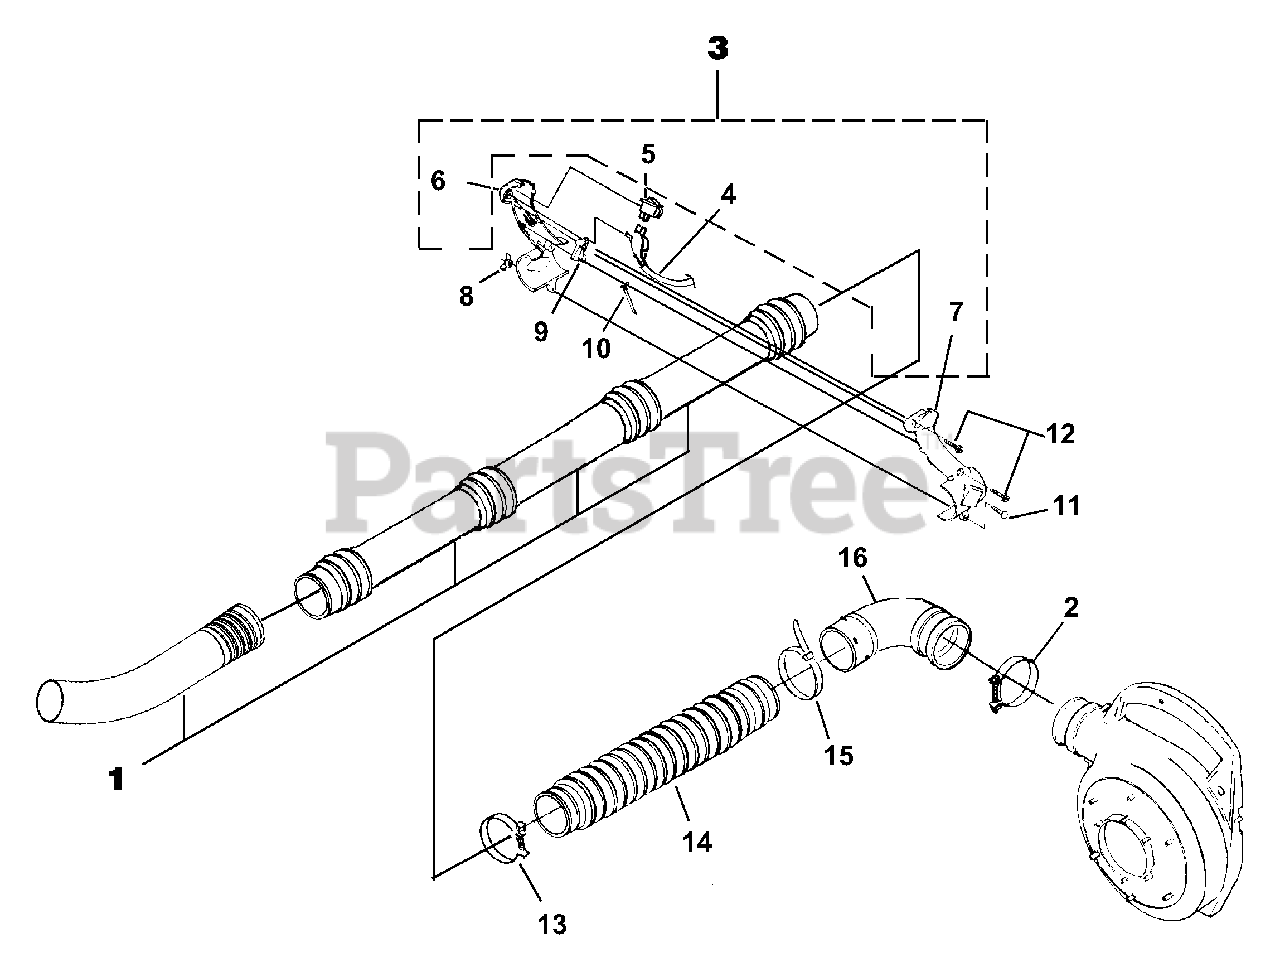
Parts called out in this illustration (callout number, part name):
1	BLOWER TUBE KIT
2	CLAMP
3	HANDLE & SWITCH KIT
4	CABLE-Throttle w/ Ignition Leads
5	SWITCH
6	HANDLE-Control (Right)
7	HANDLE-Control (Left)
8	NUT - Wing (10-24)
9	TRIGGER
10	LATCH-Trigger
11	BOLT-Rib Neck, Rnd. Hd. (10-24 X 7/8")
12	SCREW-Thread Form. (10-14 X 3/4")
13	CLAMP (#87)
14	BELLOWS-Plastic
15	CABLE-Tie
16	ELBOW-Curved
